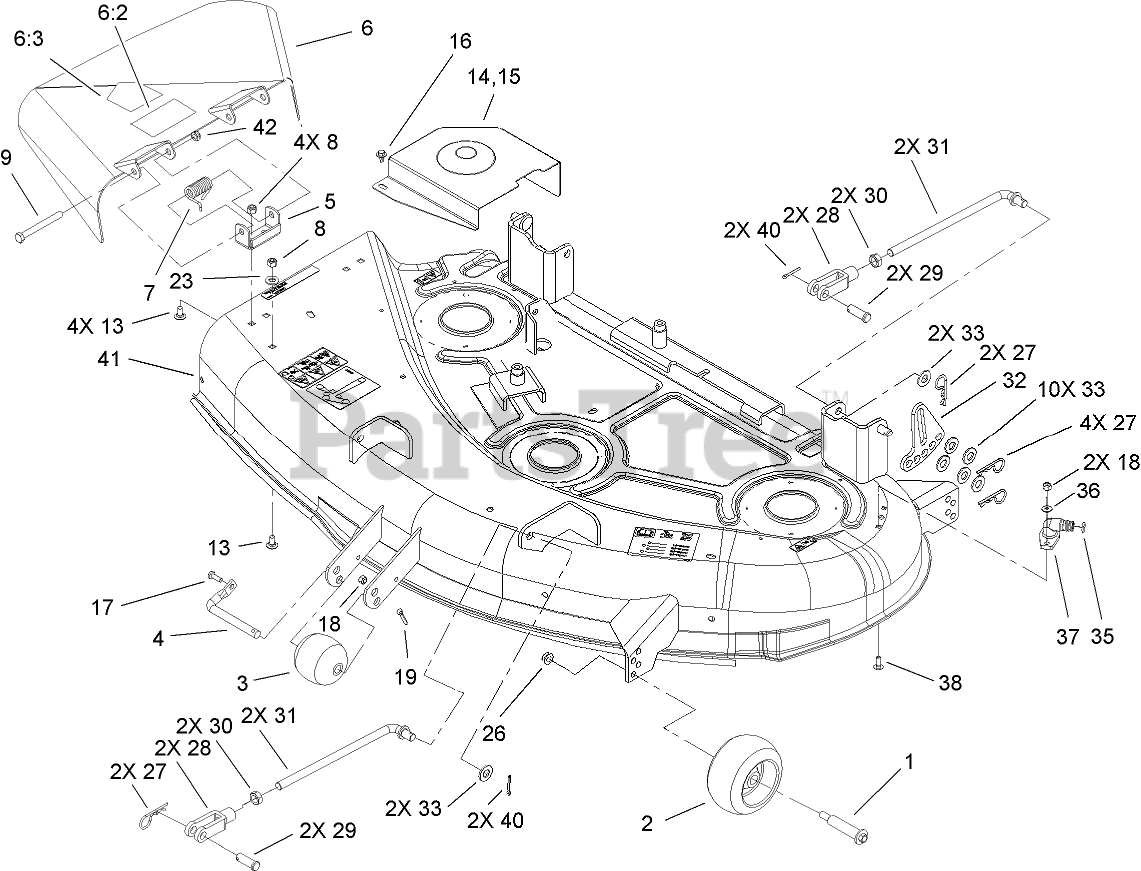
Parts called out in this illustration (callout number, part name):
1	BOLT-SHOULDER
2	ROLLER-SCALP, ANTI
3	ROLLER
4	Shaft-Roller
5	BRACKET-PIVOT
6	DEFLECTOR ASM
6:2	DECAL-DANGER
6:3	DECAL-DANGER
7	SPRING
8	NUT-LOCK, NI
9	SCREW-HH
13	SCREW-CARR
15	COVER-BELT, RH
16	SCREW-HHFTF
17	SCREW-HH
18	NUT-LOCK, NI
19	PIN-COTTER
23	WASHER-FLAT
26	NUT-LOCK, NI
27	PIN-COTTER
28	CLEVIS
29	PIN-CLEVIS
30	NUT-JAM
31	ROD-TRUNION
32	LINK-HOC, ADJUSTING
33	WASHER-FLAT
35	O-RING
36	WASHER-FLAT
37	FITTING-WASHOUT
38	BOLT-CARR
40	PIN-COTTER
41	44 INCH DECK ASM
42	NUT-HEX
